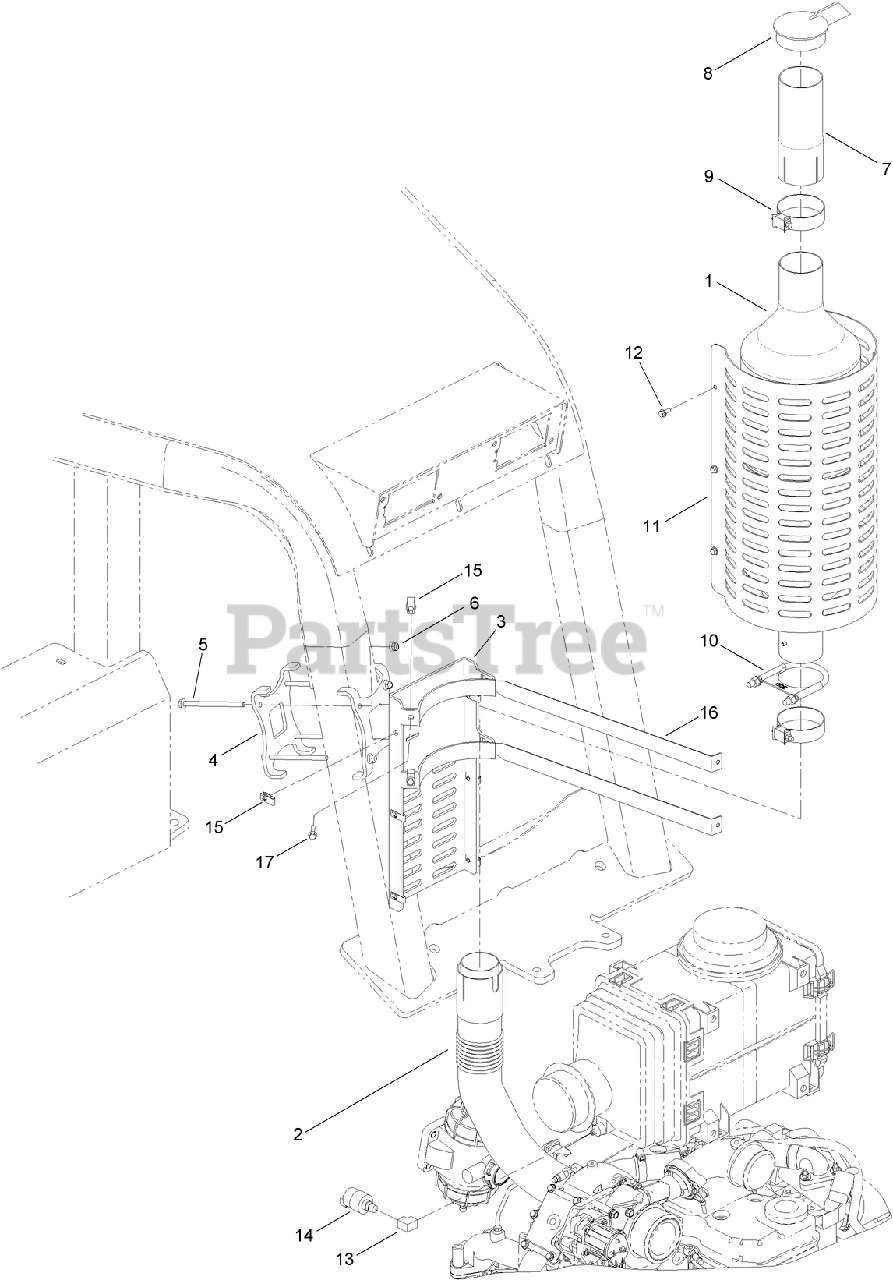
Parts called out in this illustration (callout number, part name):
1	MUFFLER
2	PIPE-TURBO
3	MOUNT-MUFFLER
4	PLATE-BENT
5	SCREW-FLANGE, METRIC
6	NUT-LOCK, HHF
7	TUBE-EXHAUST
8	CAP-RAIN
9	CLAMP-TORCTITE
10	CLAMP-GUILLOTINE
11	SHIELD-MUFFLER
12	SCREW-HHF
13	FITTING-ELBOW, 90
14	SWITCH ASM
16	STRAP-MUFFLER
17	SCREW-HHF
